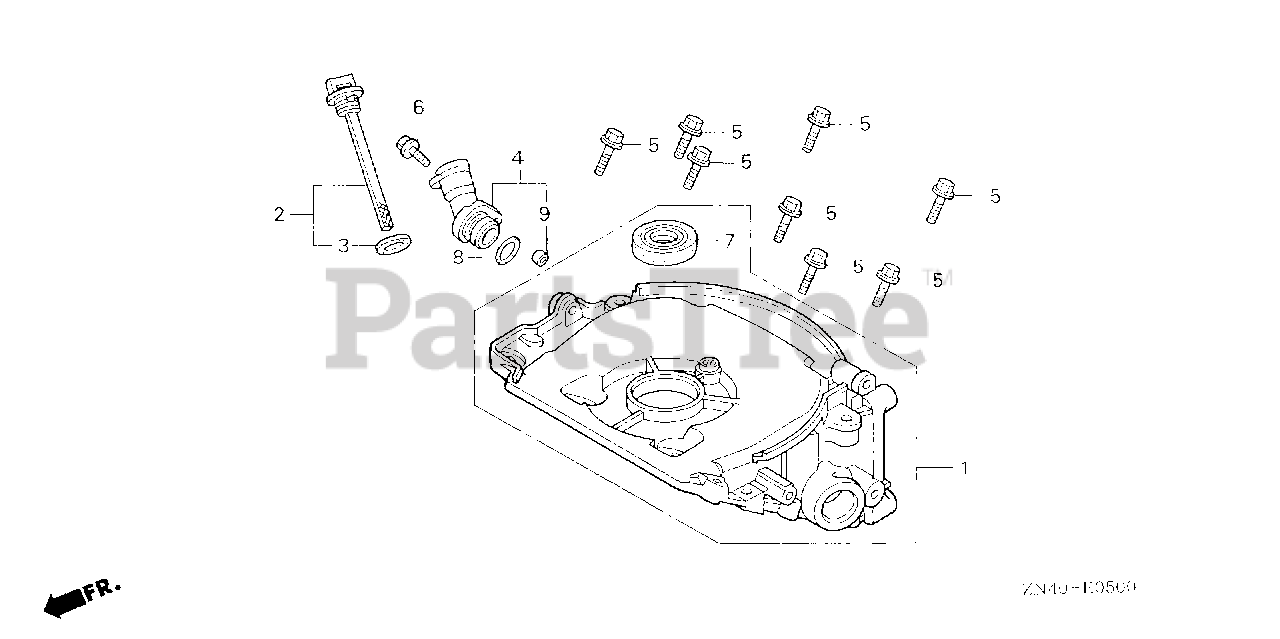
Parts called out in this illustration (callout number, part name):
1	CASE ASSY., OIL
2	CAP ASSY., OIL FILLER
3	GASKET, OIL FILLER CAP
4	EXTENSION, OIL FILLER
5	BOLT, FLANGE (5X23)
6	BOLT, FLANGE (5X14)
7	OIL SEAL (17X27X5) (KOYO)
8	O-RING (21.2X2.4) (ARAI)
9	COLLAR, TOP COVER
